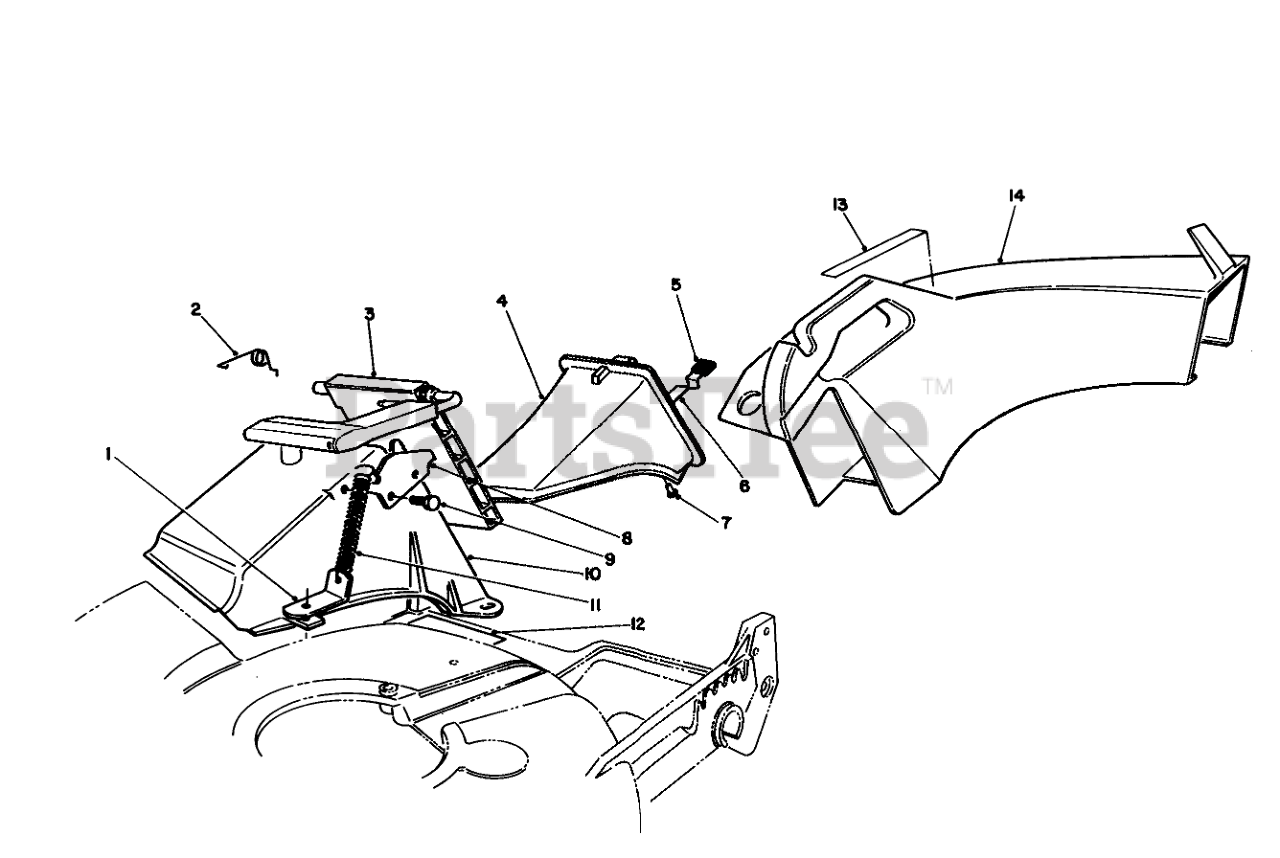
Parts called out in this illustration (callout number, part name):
1	Bracket-Spring
2	RETAINER-DOOR
3	DOOR ASSEMBLY
4	Plug Assembly (Incl. Ref. #5-7)
5	GRIP-LATCH
6	LATCH-PLUG, DISCHARGE
7	RIVET-HEAD, FLAT
8	DOOR LATCH PLATE
9	SCREW-PLASTITE
10	DISCHARGE TUNNEL
11	SPRING-DOOR
12	DECAL - CAUTION
13	DECAL - WARNING
14	CHUTE
